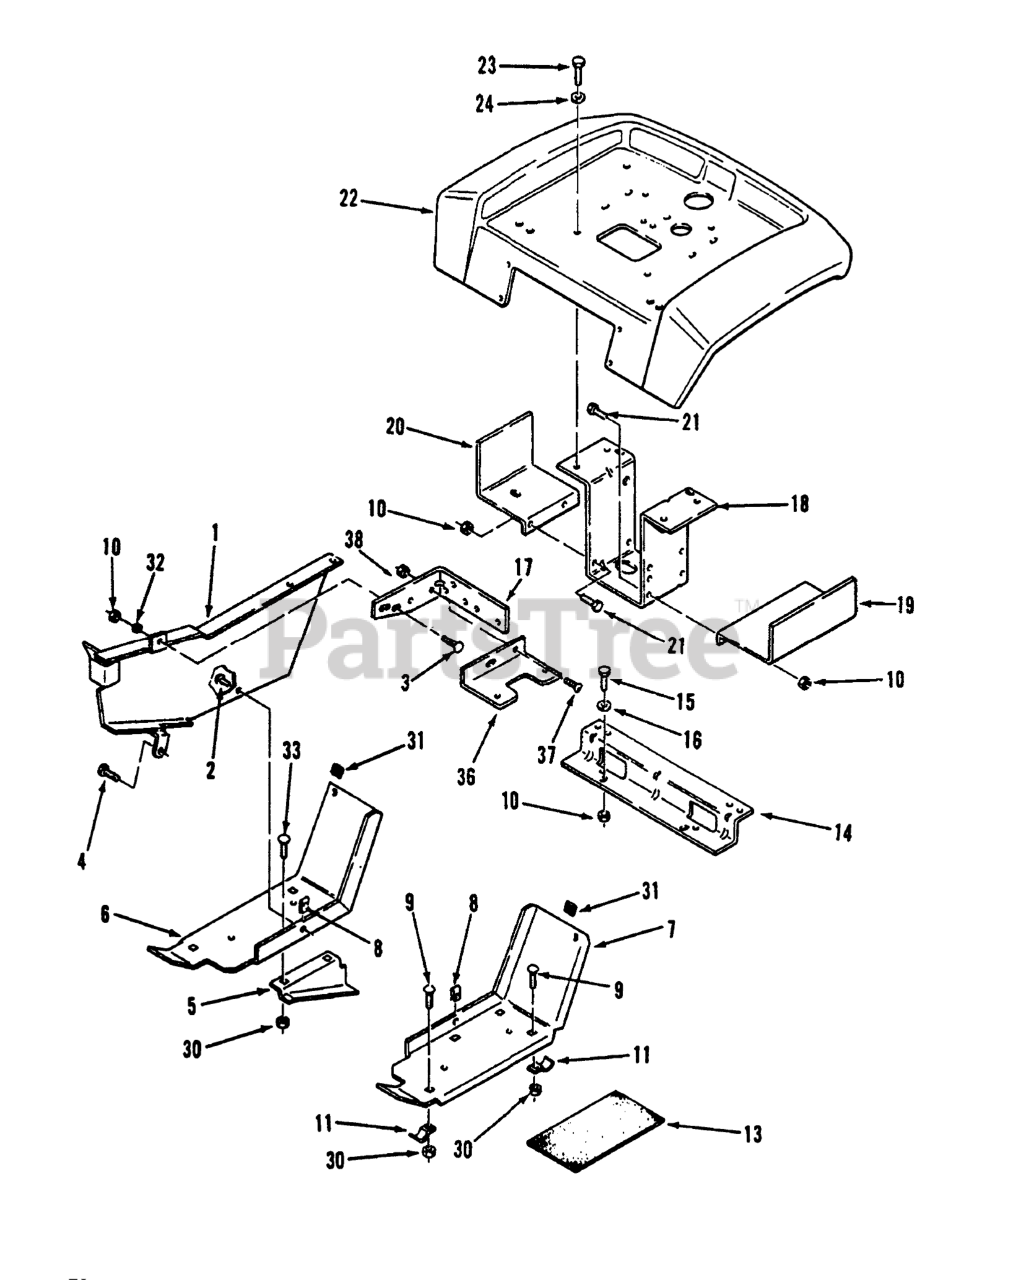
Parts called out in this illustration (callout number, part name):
1	Belt Guard
2	Screw
3	BOLT-CARR
4	SCREW
5	GUID-LOWER BLTR
6	Footrest-RH
7	FOOTREST LH R
9	BOLT-CARR
10	NUT-LOCK, NI
11	BRACKET
13	PAD FOOTREST
14	BRACKET-FENDER B
15	SCREW-HH
16	WASHER-PLAIN
17	BRACKET-BELTB
18	Bracket-Fender Support
19	Fuel Tank Support LH
20	Support-FueITank RH
21	SCREW-HH
22	WASHER-PLAIN
23	SCREW
24	WASHER 5/16 SAE
30	NUT-LOCK, NI
31	BUMPER SJ5514 BLACK
32	NUT-PUSH
33	BOLT-CARR 5/16 SN
36	BRKT-FUS HLDERB
37	SCREW-HH
38	NUT-LOCK, NI
